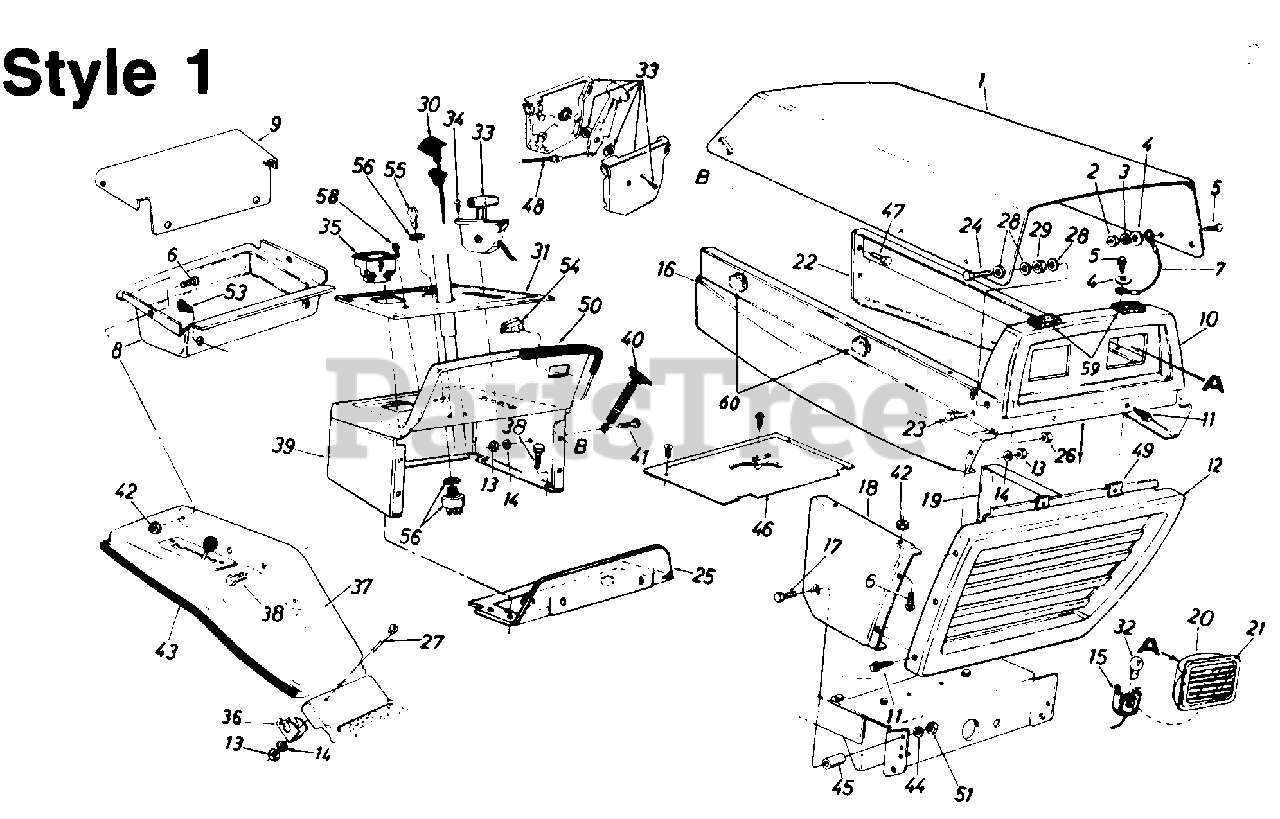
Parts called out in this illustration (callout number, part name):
3	L-Wash. #10 I.D.
4	Fl-Wash. .25" I.D. x .62"
5	Truss Scr. #10-24 x .375"
6	Truss Hd. Scr. #10-24 x .50"
7	Hood Stop
8	Tool Tray
11	Hex AB-Tap Scr. #10 x .50"
14	L-Wash. 1/4" I.D.
15	Twist Lock-Lamp Socket
18	R.H. Lower Side Panel
21	Headlight Lens
24	Hex Bolt 3/8-16 x 1.00" Lg.
25	Support Brkt.
26	Hex Cent. L-Nut 3/8-16 Th.
27	Carriage Bolt 1/4-20 x 2.00"
28	Fl-Wash. .380" I.D. x 1.00"
29	Rubber Washer
30	Choke Control
31	Dash Panel Insert
32	Head Lamp
33	Throttle Box Ass'y.
34	Truss Mach. AB-Tap Scr. #10 x .5" Lg.
35	Ammeter
36	Fender Clamp
37	Fender
38	Hex Bolt 5/16-18 x .75" Lg.
39	Dash Panel Ass'y.
40	Hood Latch Ass'y.
41	Hex Bolt 1/4-20 x .50" Lg.
42	Hex Sems Nut #10-24 Thd.
43	Trim Strip-57" Lg.
44	Belleville Wash. .34" I.D.
45	Spacer
46	Shift Cover
47	Hex Wash. Hd. AB-Tap Scr. 1/4-20 x .62
48	Throttle Control Wire
49	Speed Nut #10Z
50	Trim Strip-15"
51	Hex Nut 5/16-18 Thd.
53	Hex AB-Tap Scr. 5/16-18 x .75"
54	Light Switch
55	Ignition Key
56	Ignition Switch
58	Hex AB-Tap Scr. #8 x .5" Lg.
59	Foam Strip
60	Mtg. Clamp
